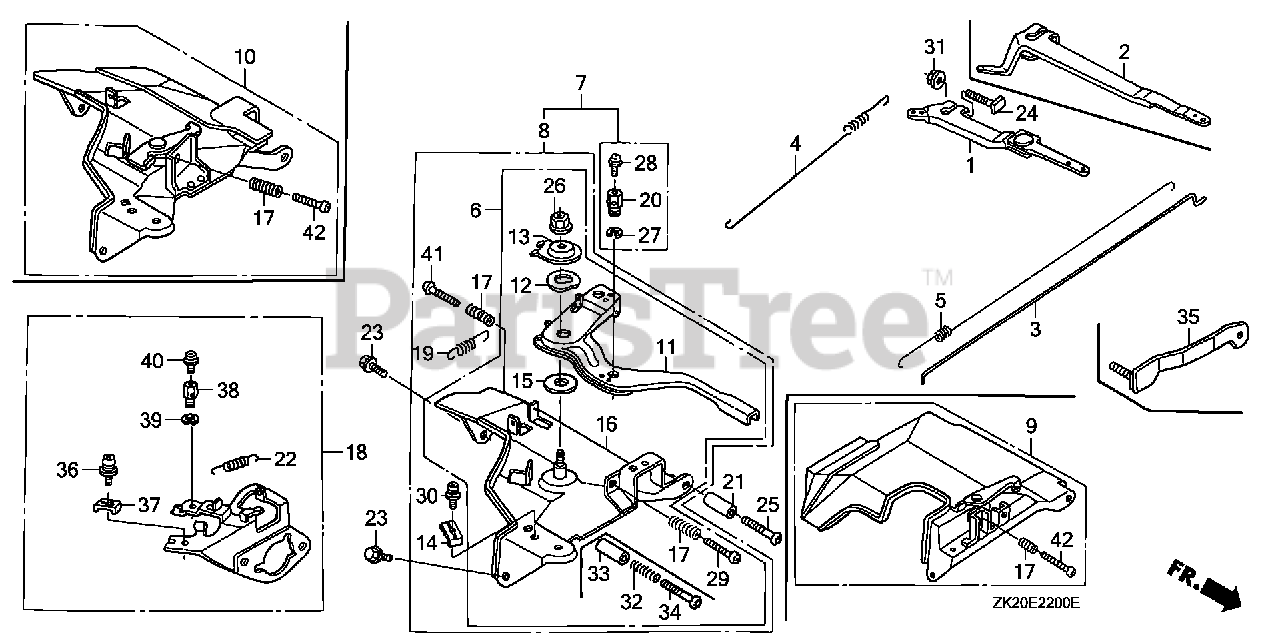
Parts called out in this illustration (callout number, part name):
2	ARM, GOVERNOR
3	ROD, GOVERNOR
4	SPRING, GOVERNOR (L=145.0MM) (WIRE DIAMETER 1.0MM)
5	SPRING, THROTTLE RETURN
8	CONTROL ASSY. (REMOTE)
11	LEVER, CONTROL
12	SPRING, LEVER
13	WASHER, CONTROL LEVER
14	HOLDER, CABLE
15	SPACER, CONTROL LEVER
16	BASE, CONTROL
17	SPRING, CONTROL ADJUSTING
19	SPRING, CABLE RETURN
23	BOLT, FLANGE (6X12) (CT200)
24	BOLT, GOVERNOR ARM
26	NUT, SELF-LOCK (6MM)
29	SCREW, PAN (5X28)
30	SCREW, PAN (5X16)
31	NUT, FLANGE (6MM)
